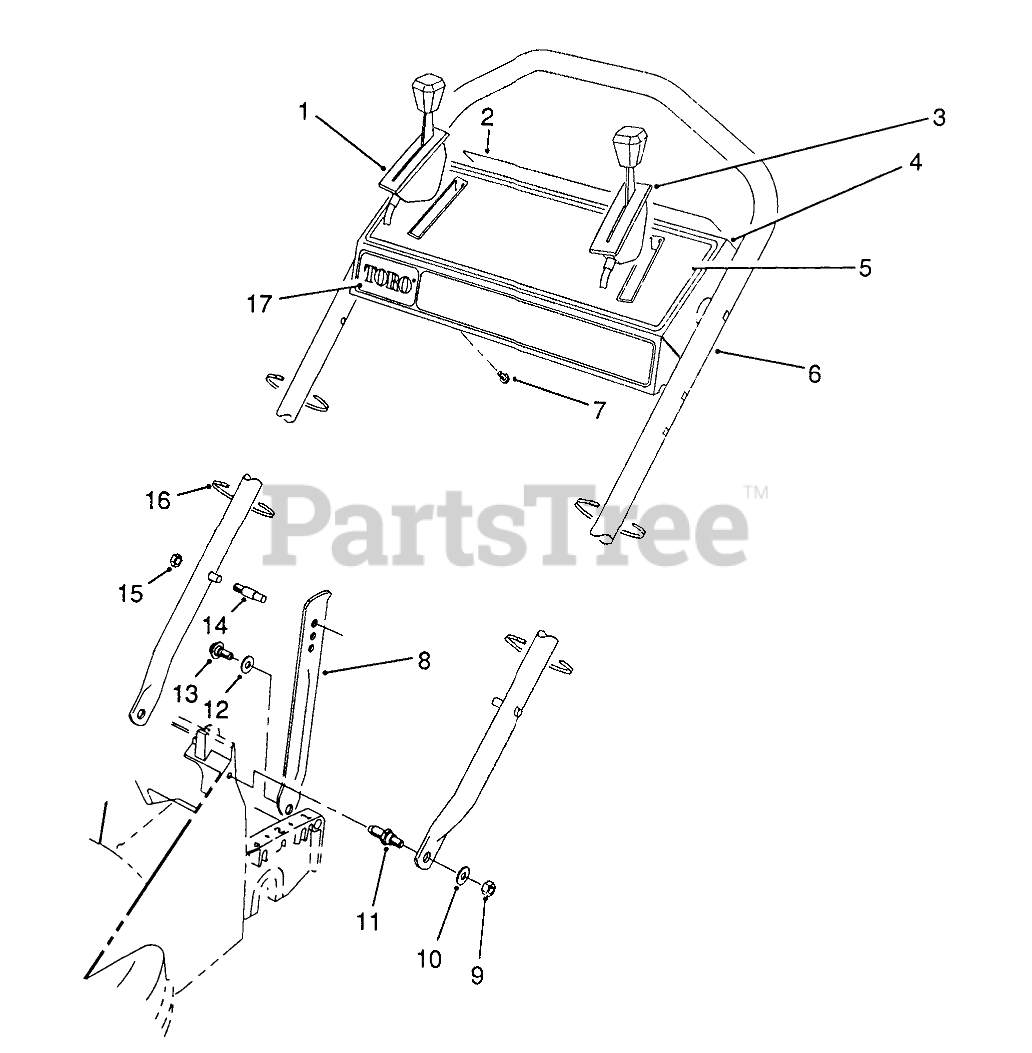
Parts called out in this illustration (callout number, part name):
1	Control-Ground Speed
2	DECAL - PANEL, REAR
3	Control-Throttle Bend Type #1 Sheath Lg. 43-3/4" Wire Lg. 2-5/8"
4	Panel-Control (Model 26680 Only)(Incl. Ref. #2 & 5)
5	DECAL - INSTRUCTION
6	HANDLE
7	SCREW-HWHTF
8	HANDLE LATCH
9	NUT-LOCK, NI
10	WASHER-PLAIN
11	SCREW - SHOULDER STUD
12	NYLON WASHER
13	SCREW-SHOULDER
14	HANDLE PIN
15	NUT-LOCK, NI
16	TIE-CABLE
17	DECAL - TORO PANEL
